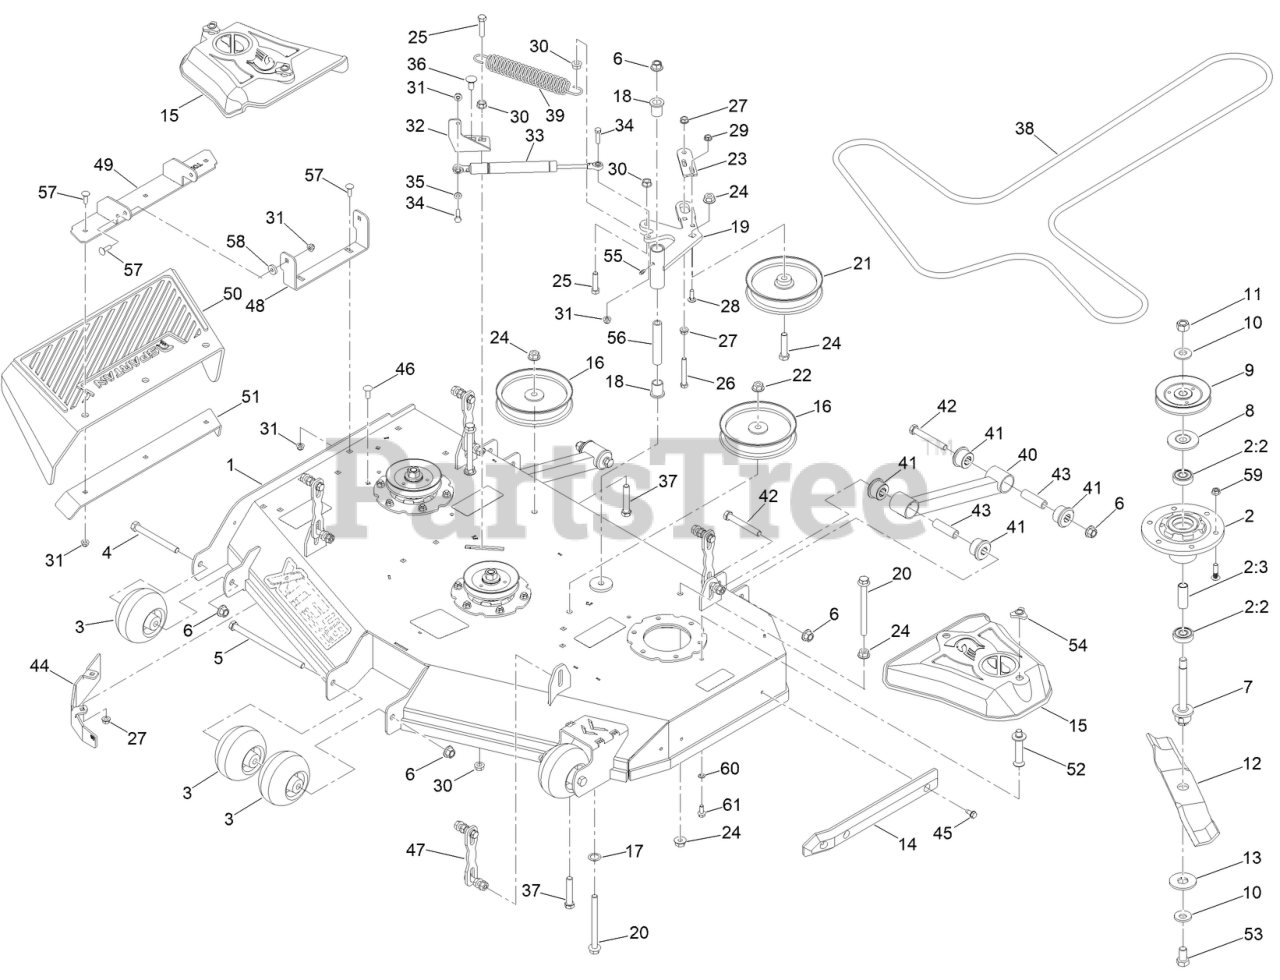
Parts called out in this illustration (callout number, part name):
1	ASM-DECK W/ DECALS
2	SPINDLE ASM 5IN DECK
2:2	BEARING
2:3	SPACER, BEARING
3	MWR ANTI-SCALP WHL W/O GREASE FITTING
4	SCREW-HH
5	1/2-13 X 8-1/2 HEX C/S GR 2 ZINC YELLOW
6	NUT-LOCK
7	SHAFT - SPINDLE
8	GUARD-BEARING TOP 0.673IN
9	PULLEY
10	M16 SPRING WASHER (39MMOD/ 3.9MM THK)
11	M16X1.5 C8.8 HEX NUT
12	BLADE-ROTARY
13	WASHER-HEX
14	MWR NYLON DECK GUARD
15	COVER BELT
16	6-3/4IN IDLER PULLEY 15/16IN SPACER ASSY
17	.767IDX1.125ODX.016 THK TRIP WV WASHER
18	3/4IN ID X15/16IN OD X 1-1/8IN FLNG BUSH
19	MWR DECK IDLER PULLEY ARM ASSY PAINT
20	1/2-13 X 5-1/2 HEX FLANGE BOLT GR 8 ZY
21	6-3/4IN IDLER PULLEY 7/16IN SPACER ASM
22	SCREW-HH
23	DECK IDLER PULLEY BELT RETNR BRKT PAINT
24	NUT-HHF
25	SCREW-HH
26	SCREW-HH
27	NUT-HHF, WHIZ
28	BOLT-CARR
29	NUT-HF
30	NUT-HF
31	NUT-HF, NI
32	48 BELT DECK IDLER DAMPR MTG BRKT PAINT
33	IDLER GAS SPRING
34	SCREW-HH
35	.312IDX.625ODX.062 THK THRUST BRG OI BRZ
36	SCREW-CARR
37	1/2-13 X 2-3/4 HEX FLANGE BOLT (GR.8) YZ
38	48 MWR DECK BELT HB X 144IN EFF LENGTH
39	MWR DECK SPRING
40	RZ MWR DECK STABILIZER ASSY PAINTED
41	RED A80 SUSP BUSHING
42	1/2-13 X 3-3/4 HEX C/S (GR.5) ZC/YEL
43	UTV A-ARM BUSHING SLEEVE
44	BAFFLE-WIPER 48
45	SCREW-HWH, THREAD CUT
46	SCREW-CARR
47	RZ MWR DECK LINK ASM
48	MWR CHUTE MTG BRKT PAINTED
49	2020 RZ MWR DECK CHUTE HINGE ASSY PAINT
50	RZ MWR RUBBER DISCHARGE CHUTE
51	RZ MWR DECK CHUTE HNGE BACKR BRKT PAINT
52	PIN-BELT COVER
53	M16X1.5-30MM C10.9 HEX BOLT
54	NUT-KNOB
55	1/4IN DRIVE TYPE GREASE FITTING YZ
56	MWR INNER IDLER SPACER
57	5/16-18 X 1 CARRIAGE BOLT GR 8 YZ
58	.312 ID X .875OD X .1875 THK F/W NYL
60	WASHER-LOCK
61	SCREW-HHF
